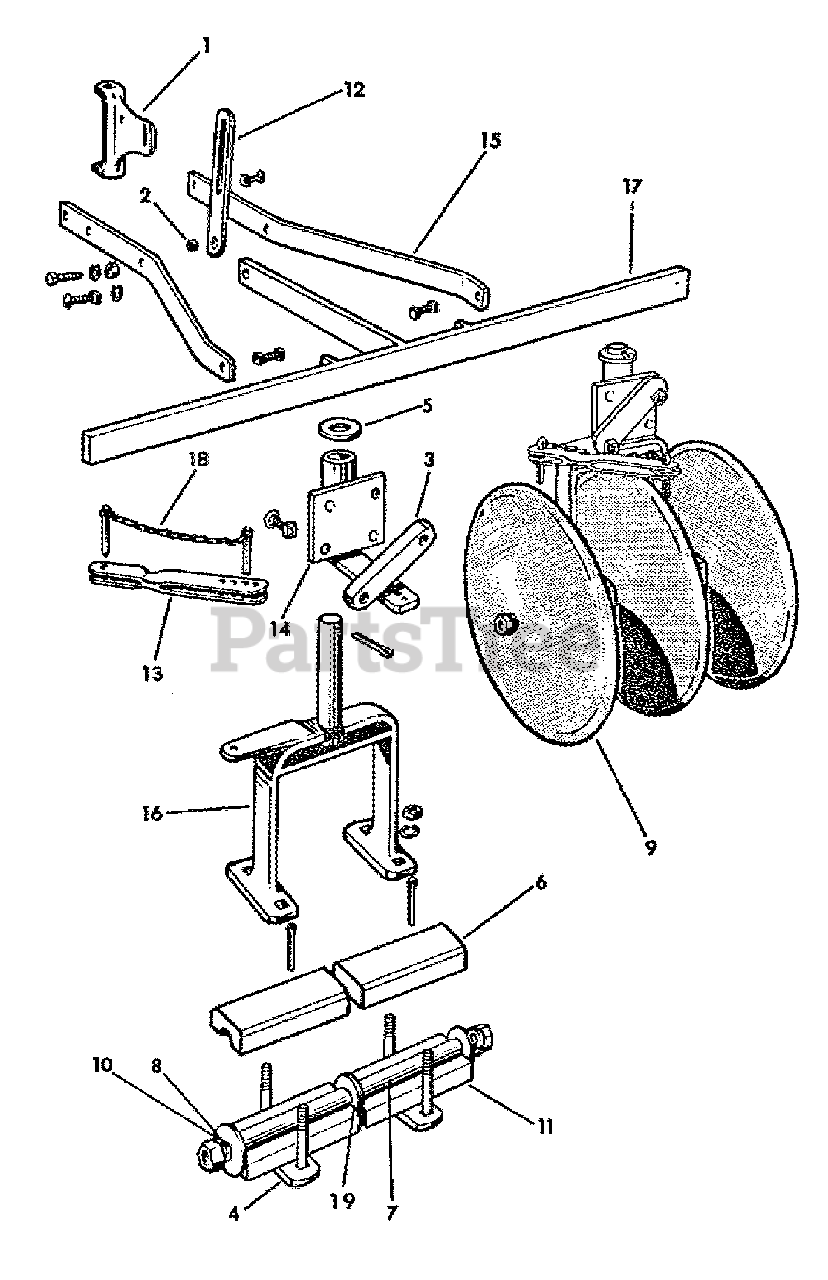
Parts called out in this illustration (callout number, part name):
1	DRAW BAR END
2	ADJUSTMENT LINK SPACER
3	CLAMP CLIP
4	BEARING CLIP
5	POST WASHER
6	UPPER BEARING BLOCK
7	DISC SPACER
8	AXLE - 8 Disc Only
9	12" DISC BLADE
10	AXLE - 6 Disc Only
11	LOWER BEARING BLOCK
12	TILT ADJUSTMENT LINK
13	ANGLE ADJUSTMENT STRAP ASSEMBLY
14	CLAMP ASSEMBLY
16	ARCH ASSEMBLY
17	CROSS BAR ASSEMBLY
18	CHAIN, 6"
19	SPECIAL WASHER
